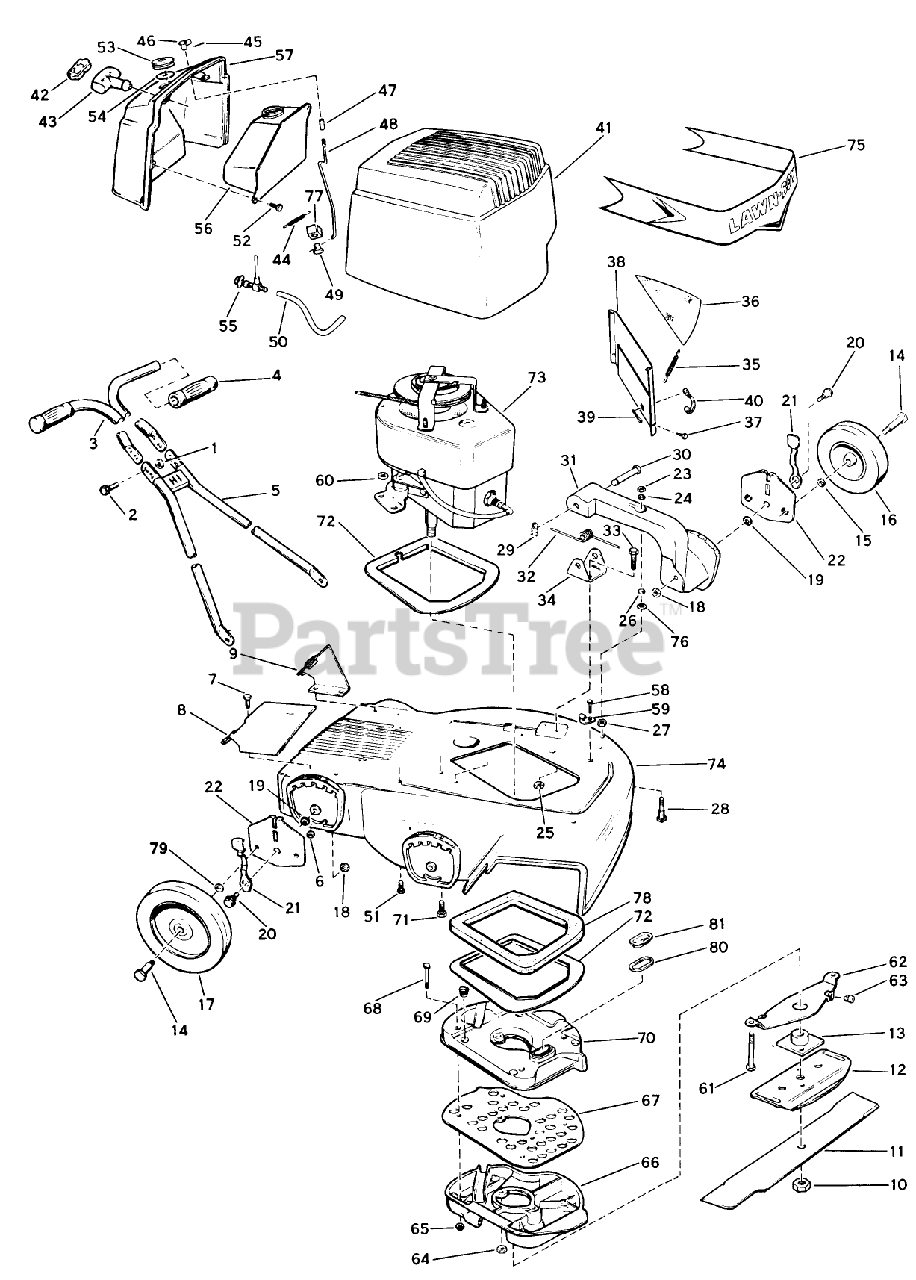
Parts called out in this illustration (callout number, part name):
1	STOP NUT
4	HANDLE GRIP
10	NUT-BLADE
13	PLATE AND COLLAR ASM
14	BOLT WHEEL
15	WASHER WROUGHT
23	STOP NUT
24	Washer-Level Ride, Fiber
25	STOP NUT
26	Washer-Level Ride Arm
27	Jam Nut
28	Bolt-Level-Ride Arm
29	Hair Pin-Level Ride Arm
30	Pin-Level Ride Arm
32	Spring-Level Ride Arm
33	Screw-Level-RideArm Bracket
34	Bracket-Level Ride Arm
36	Screen-Sound Trap
37	Screw-Thread Cutting
38	Shield Sound Trap
45	Cotter Pin-Choke Knob
46	KNOB, CHOKE BAR
48	Rod-Choke
49	Pivot-Choke Rod (Nylon)
52	Screw-Thread Cutting
53	Gas Cap
57	Bonnet-Rear
58	Screw-Thread Cutting
59	Latch-Bonnet
61	Screw-Engine Mtg., Long
62	Bracket-Crankshaft Limit Stop
63	Bumper-Crankshaft Limit Stop
64	Nut-Muffler to Crankcase Studs
65	LOCKNUT E
66	Muffler-Bottom
67	Gasket-Muffler
68	Bolt-Muffler
69	Spring-Muffler
70	Muffler-Top
72	Seal-Dust
74	Housing, 19"
75	Decal-LAWN-BOY
77	Retainer-Choke Rod
78	Gasket-Dust Seal
79	WASHER WROUGHT
